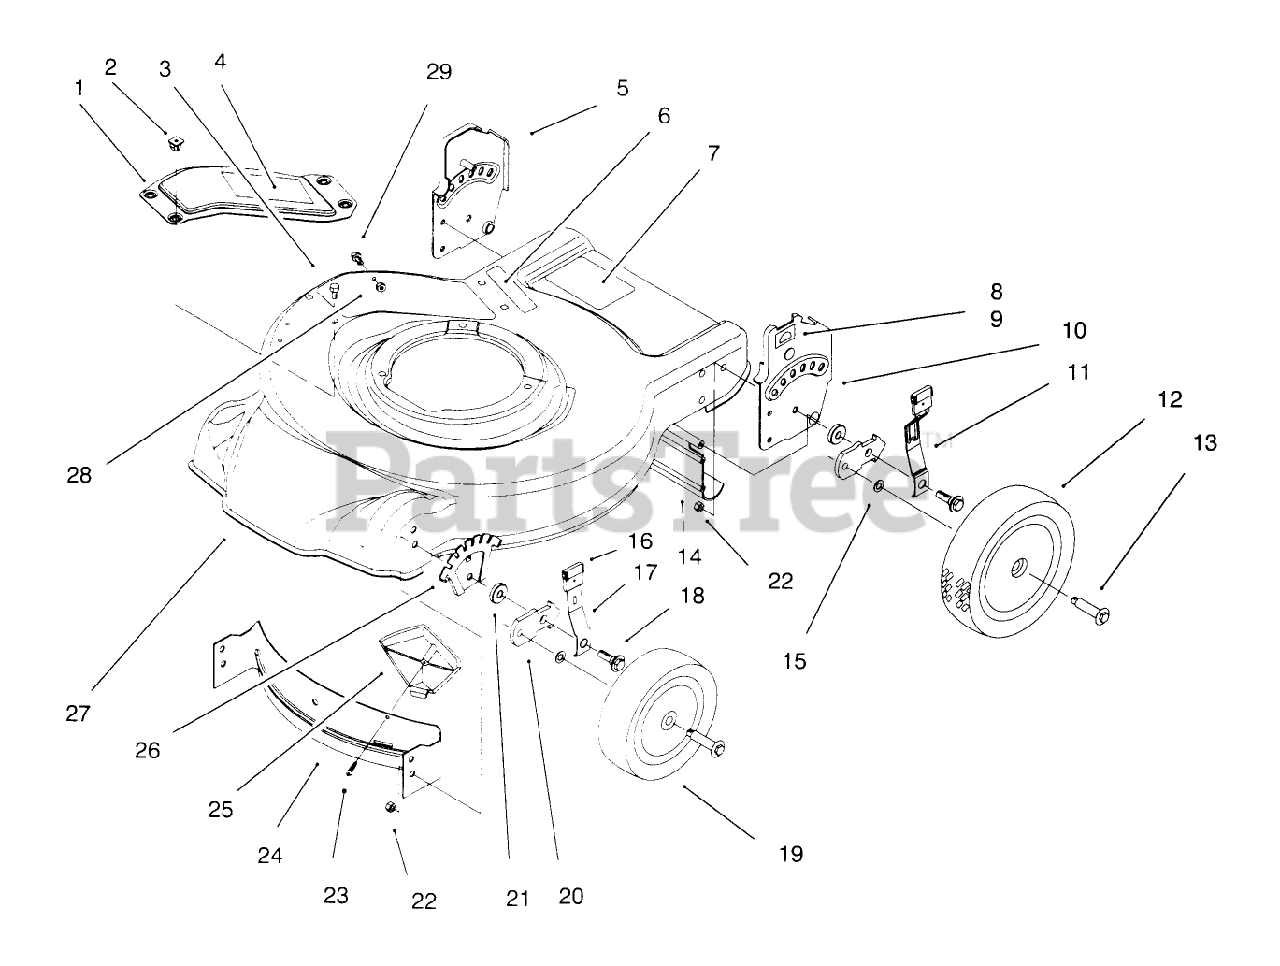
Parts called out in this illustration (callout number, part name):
1	COVER W/DECAL
3	SCREW-HWH
4	DECAL - COVER
5	ASM - RH HANDLE BRACKET
8	DECAL-HOC, RH
10	ASM - LH HANDLE BRACKET
11	REAR SPRING ARM ASM
12	WHEEL ASM
13	BOLT-SHOULDER
14	SHIELD-TRAILING
15	WASHER
16	KNOB-LEVER, HEIGHT ADJUSTMENT
17	ARM-FRONT SPRING
18	SCREW-SHOULDER, HWH
19	WHEEL ASM
21	WASHER
22	NUT-LOCK, NI
23	SCREW-PPH
25	KICKER-FRONT
28	NUT-LOCK, NI
